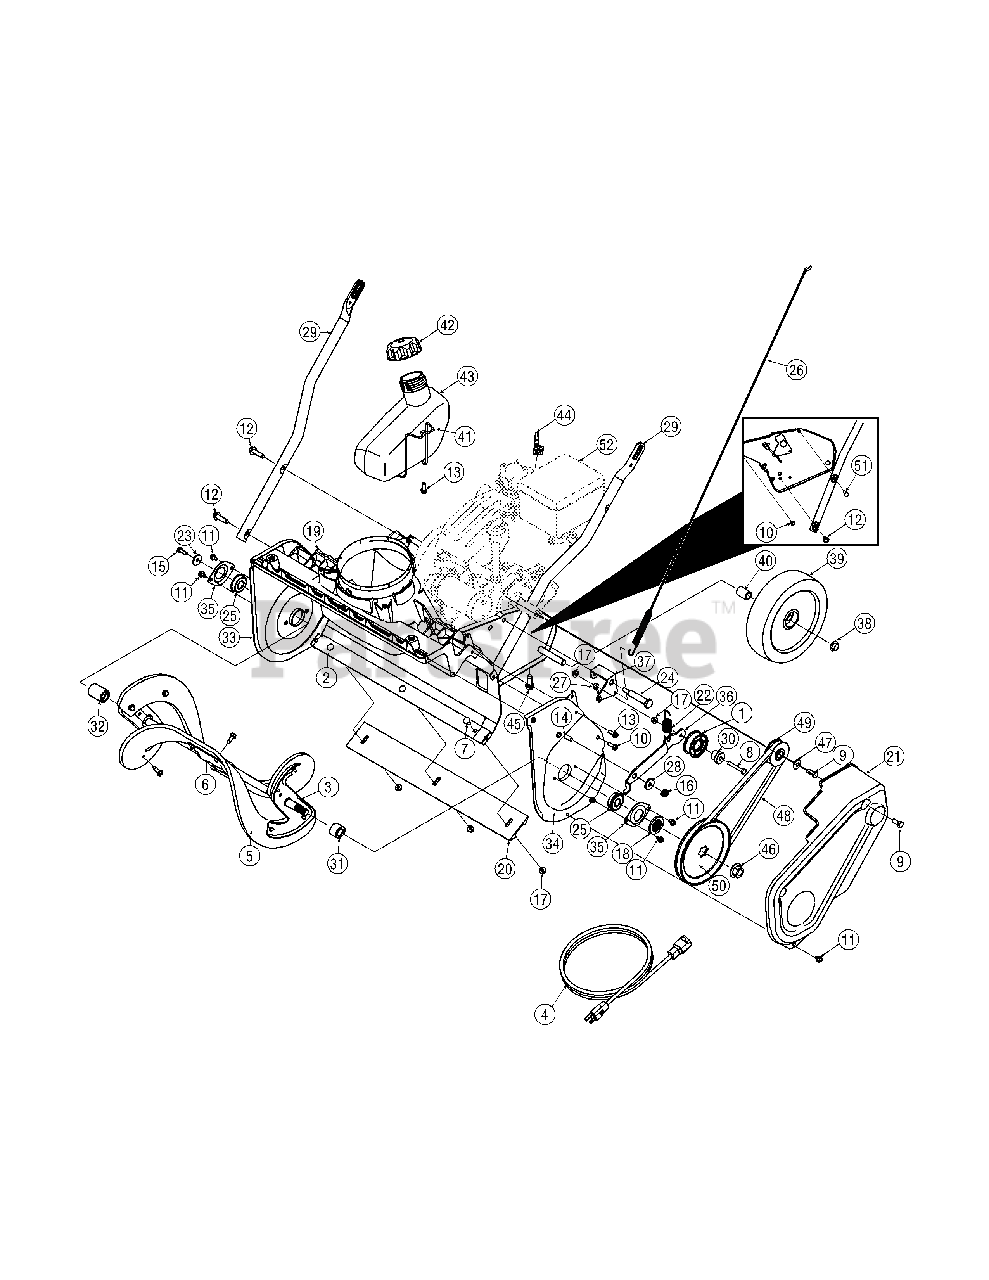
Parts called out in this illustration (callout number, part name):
1	Idler Pulley Assembly
2	Frame
3	Auger Assembly Complete
4	3-Prong Extension Cord
5	Auger Paddle Replacement Kit
6	Center Auger Bracket
7	Carriage Screw, 1/4-20 x .62
8	Hex Screw, 1/4-20 x 1.757
9	Hex Lock Screw, 5/16-24 x .750
10	Hex Washer Screw, 1/4-20 x .750
11	Hex Washer Screw, 1/4-20 x .375
12	Hex Washer Screw, 5/16-18 x 1.250
13	Hex Washer Screw, 1/4-15 x .750
14	Hex Screw, 5/16-18 x .75
15	Hex Lock Screw, 1/4-20 x .750
16	Flange Lock Nut, 5/16-18
17	Flange Lock Nut, 1/4-20
18	Pulley Hub
19	Chute Adapter
20	Shave Plate
21	Belt Cover
22	Extension Spring, .70 x 3.035
23	Flat Washer, .265 x .938 x .120
24	Shoulder Bolt, 5/16-24 x .496 x 2.18
25	Ball Bearing, .625 x 37 x 12
26	Clutch Cable
27	Drive Cable Wire Support
28	Shoulder Spacer
29	Lower Handle
30	Shoulder Spacer, .260 x .785 x .538
31	LH Auger Spacer
32	RH Auger Spacer
33	RH Auger Plate
34	RH Auger Plate
34	LH Auger Plate
35	LH Auger Plate
35	Bearing Cup
36	Bearing Cup
36	Idler Bracket
38	Push Cap, 1/2
39	Wheel, 8 x 1.7
40	Sleeve Spacer, .525 x .78 x 1.00
41	Gas Tank Wire Support
42	Fuel Cap
43	Fuel Tank
44	Choke Extension Lever
45	Hex Washer Screw, 3/8-16 x 1.000
46	Flange Nut, 9/16-18
47	Flat Washer, .343 x .88 x .062
48	Belt, .500 x 35.06
49	Pulley Half, .625 x 2.25
50	Pulley, 1/2 x 6.00
51	Hex Screw, 5/16-24 x 1.25
52	Replacement Engine
